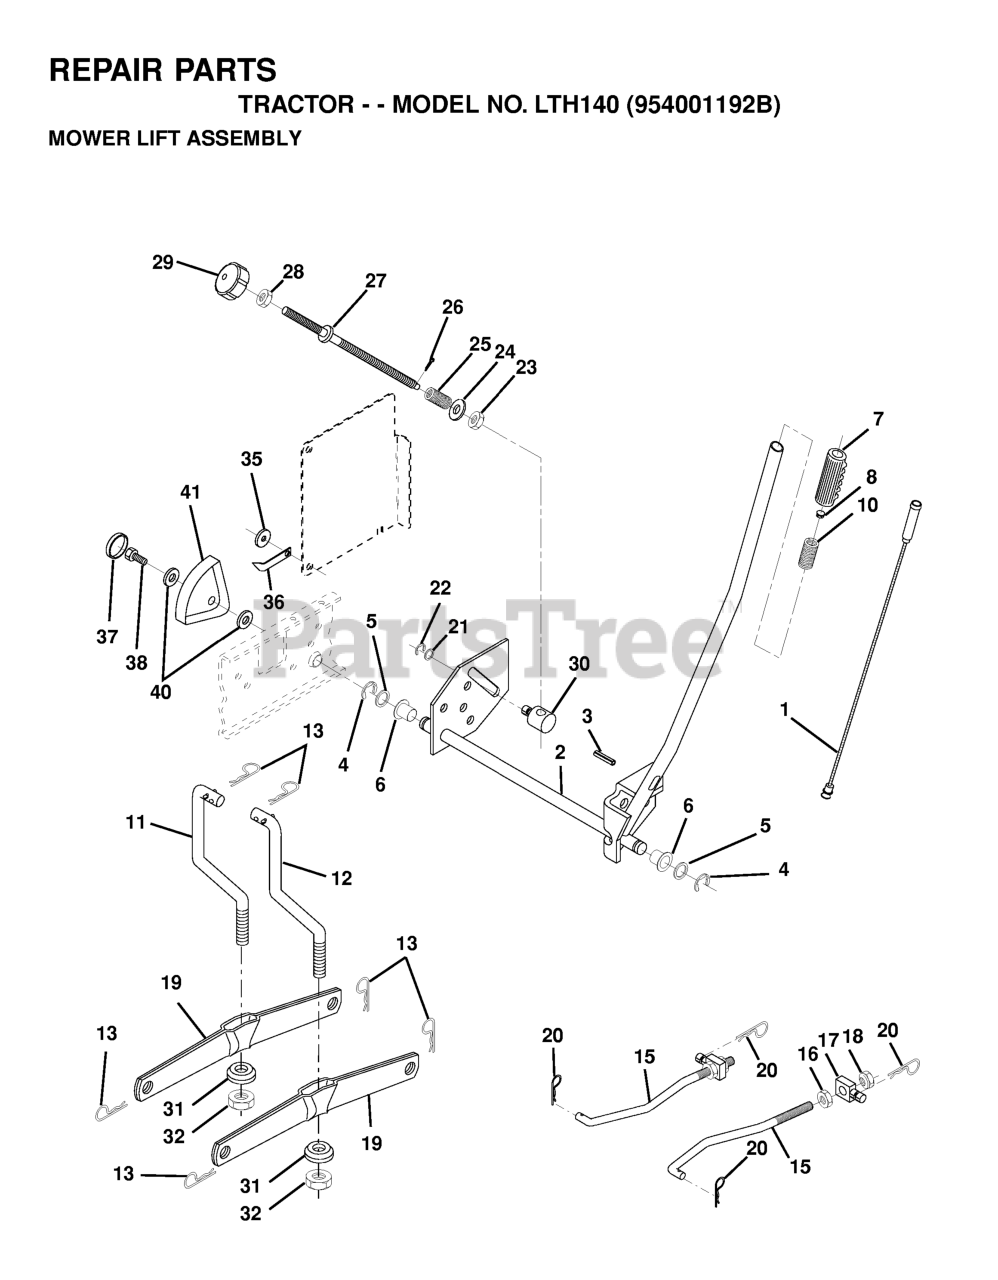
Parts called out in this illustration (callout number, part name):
1	WIRE ASM INNER
2	SHAFT ASM LIFT RH
3	PIN GROOVE
4	RETAINING RING LT
6	BEARING.NYLON
7	GRIP HANDLE
8	PLUNGER BUT KIT
10	SPRING, COMP T
11	LINK LIFT LH
12	LINK LIFT RH
13	RETAINER-SPRNG RB
15	FRONT LINK
16	NUT.HEX.JAM.1/2-13
17	TRUNION
18	NUT.LK.W/WSH.1/2.
19	ARM.REAR.SUSPENSION
20	SPRING RETAINER
21	Washer 15/32 x 3/4 x 16 Gauge
22	Ring, Klip #T5304-37
25	SPRING.COMP.INF.H
26	COTTER PIN
27	ROD.LIFT.ADJUSTABLE
28	NUT
29	KNOB INF 3/8-16
30	TRUNION LT
31	BEARING PIVOT
32	NUT CROWNLOCK 3/8-24
36	POINTER HGT
38	SCREW.THDROL.5/16-18X3/4.TTY
41	HEIGHT INDICATOR
